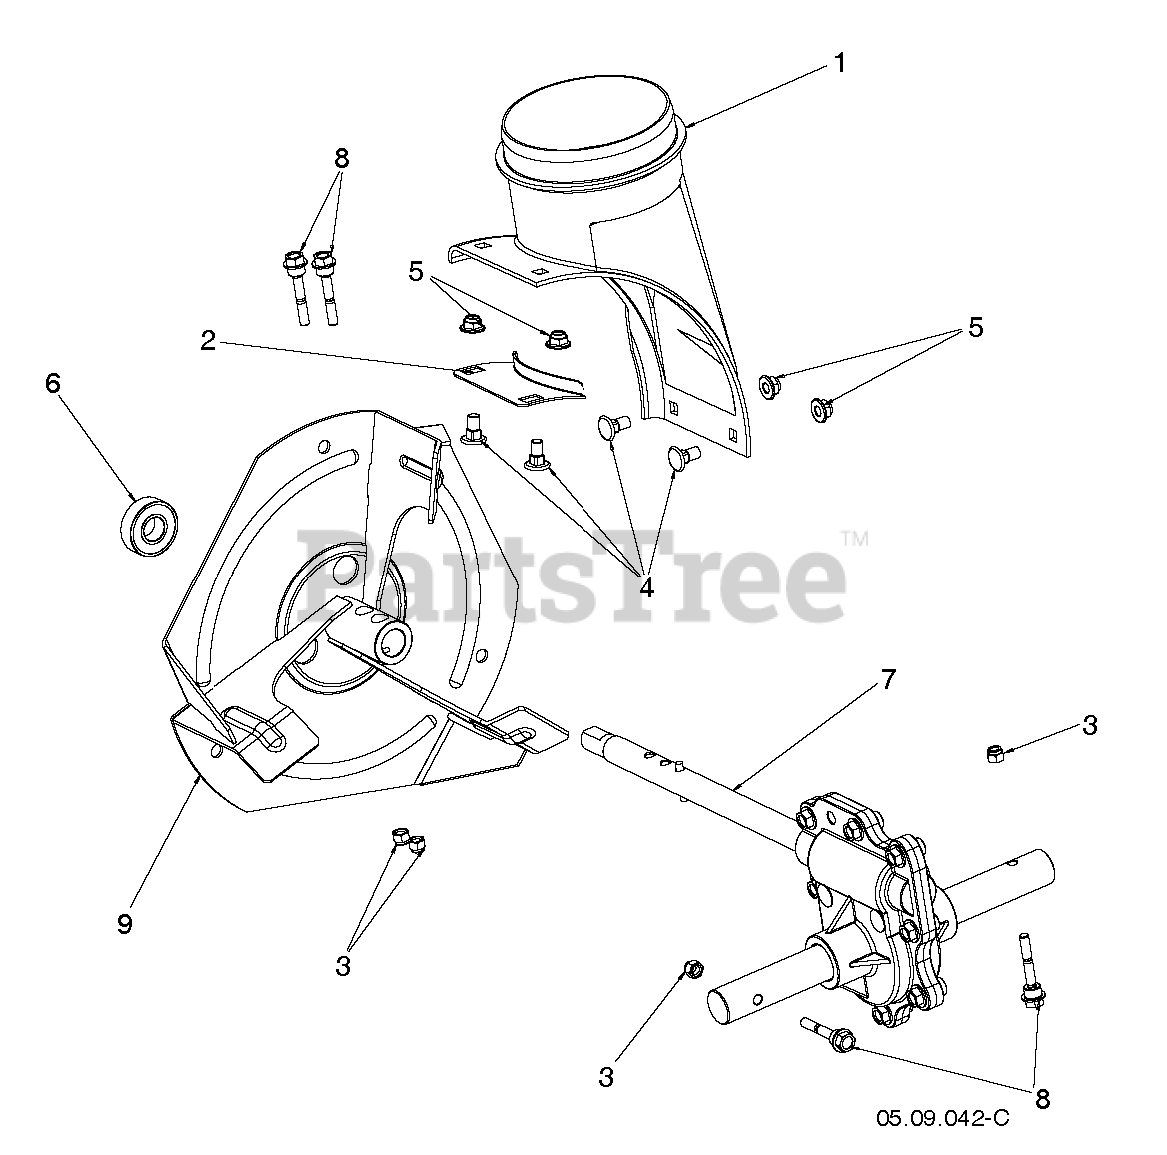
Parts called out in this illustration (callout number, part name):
1	CHUTE.DISCHARGE.BASE
3	NUT HEXAGON 1/4-20 ST ZPB
4	BOLT CARR WAFER BLK 5_16-18 X
5	NUT HEX FLG NYLOCK BLK 5_16-1
8	BOLT SHEAR HX HD 1/4-20 CLEAR
9	IMPELLER.STEEL.SNOW.BLACK
